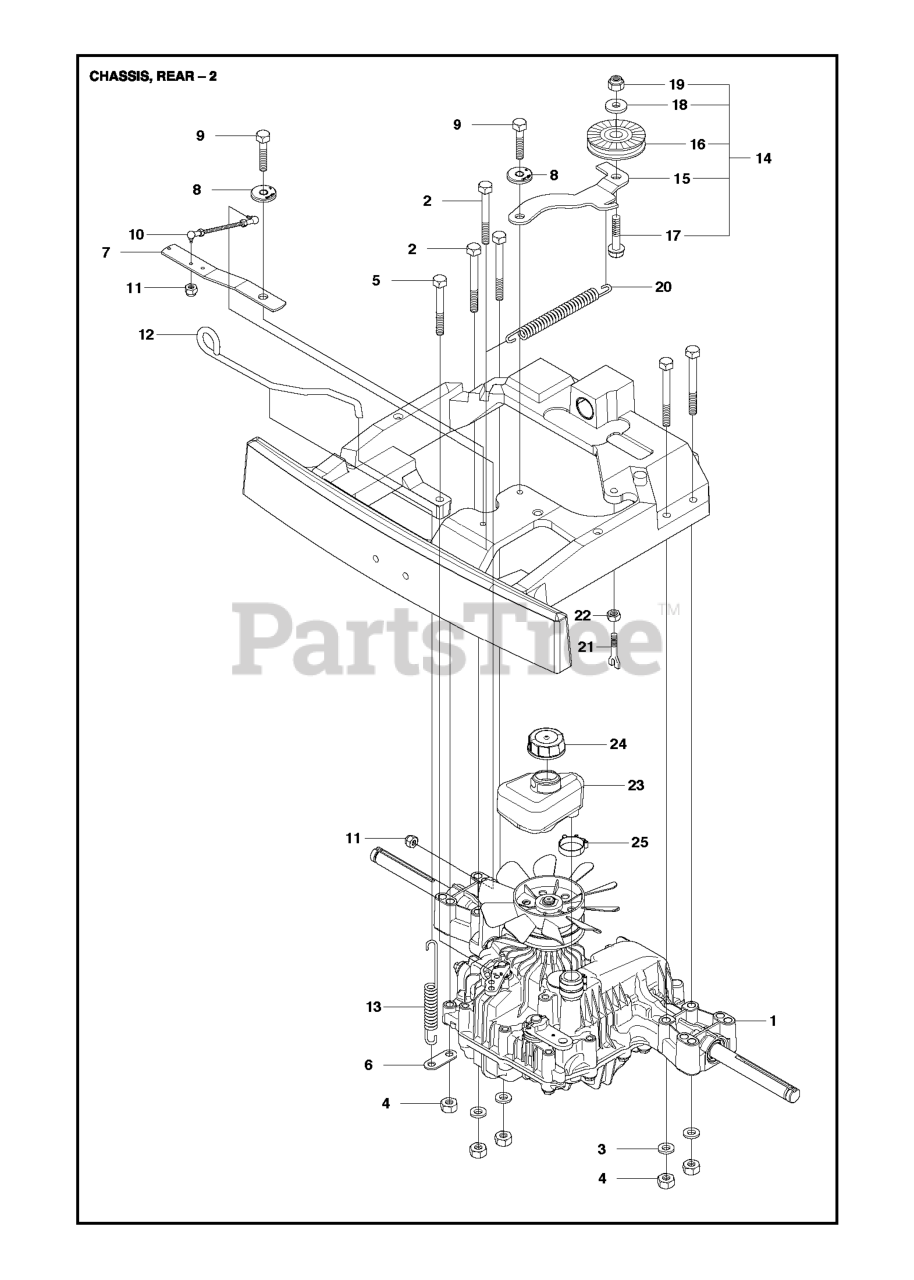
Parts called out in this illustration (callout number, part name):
1	HYDROSTAT 7A646024070
3	WASHER BRB 8.4X17
4	NUT
11	LOCKNUT M5
15	BELT TENSIONER ARM
17	SCREW
19	LOCKNUT M8
22	NUT
24	TANK CAP ASSY
25	HOSE CLAMP 20-32
